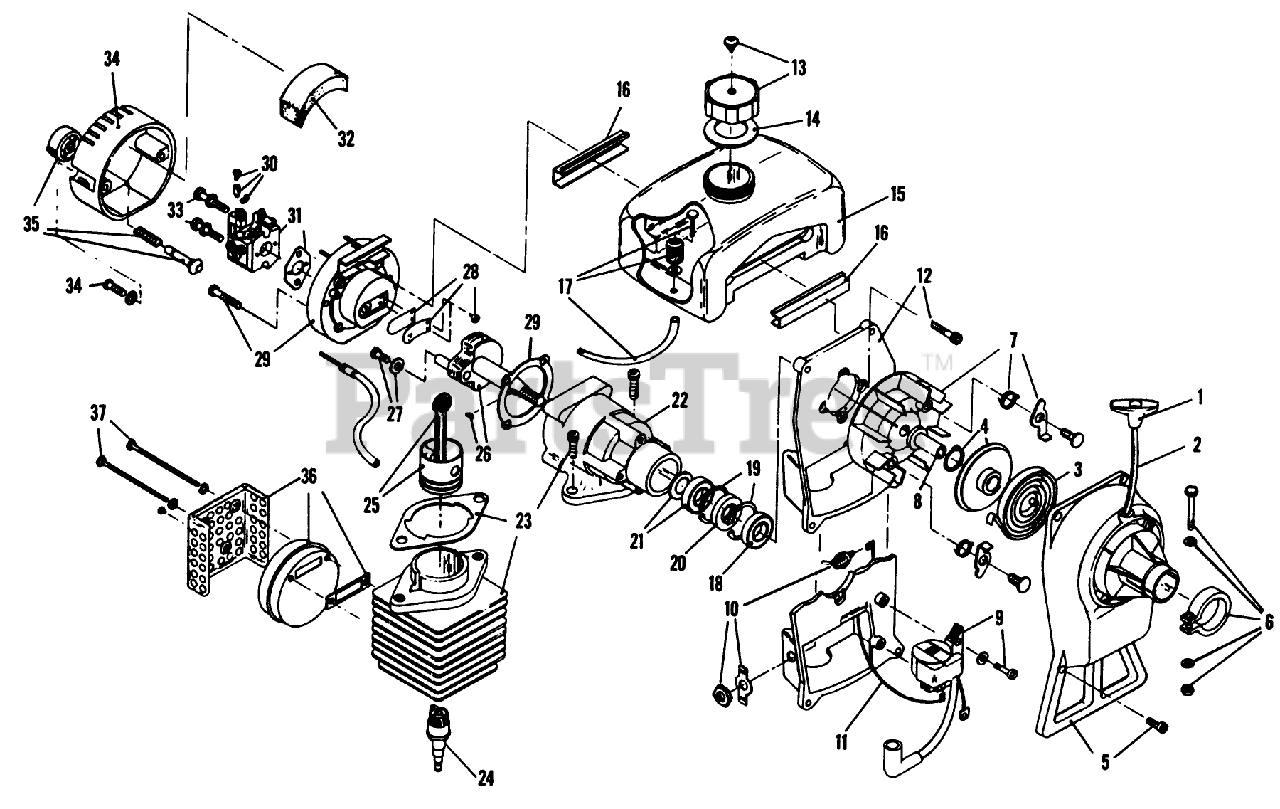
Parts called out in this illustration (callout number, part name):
1	Pull Handle
3	Recoil Spring
4	Recoil Pulley Assembly
5	Starter Housing Assembly
6	Upper Clamp Assembly
8	Square Drive Nut
9	Module Assembly
10	Switch Assembly
11	Wire Lead
12	Shroud Assembly
13	Fuel Cap Assembly
14	Fuel Cap Gasket
15	Fuel Tank
16	Tank Mounting Pads
17	PIN-BASKET
18	Outer Bearing
19	REAR BASKET ASM
21	COUPLER-RUBBER
22	Crankcase
23	Cylinder Assembly
24	Spark Plug DJ-8J
25	Piston and Rod Assembly
26	Power Shaft Assembly
27	Retainer Bolt Assembly
28	Reed Assembly
29	Carburetor Mount Assembly
31	Carburetor Assembly
32	Air Cleaner
33	Carburetor Mount Screw Assy.
34	Air Cleaner Cover Assembly
35	Choke Knob Assembly
36	Muffler Assembly
37	Muffler Bolt Assembly
38	Engine Gasket Kit
39	Engine Hardware Kit
40	E.D.M. Carburetor Repair Kit
41	Gasket-Diaphragm Repair Kit
